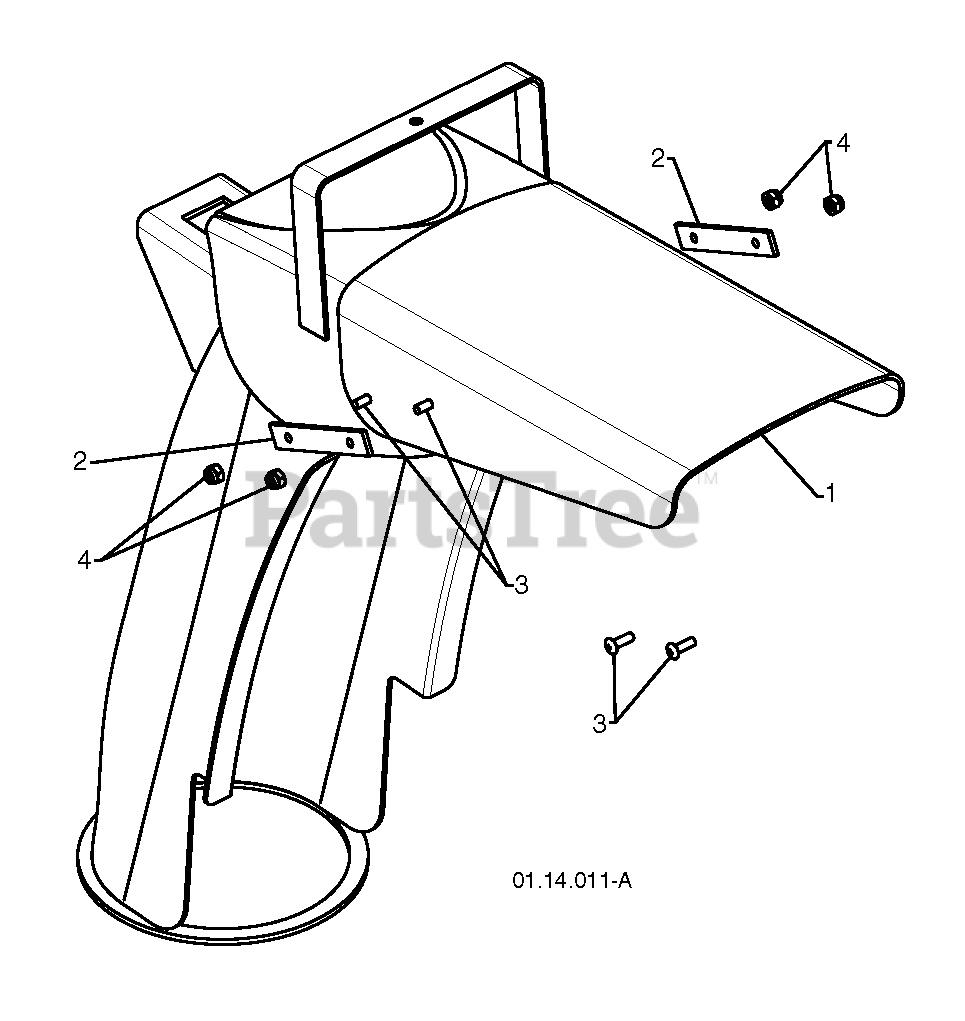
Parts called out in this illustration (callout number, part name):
1	SHIELD.DEFLECTOR.BLACK.SNOW
2	BOOT, STEERING
3	SCREW.#8.MACH
4	NUT.HEX.#8
